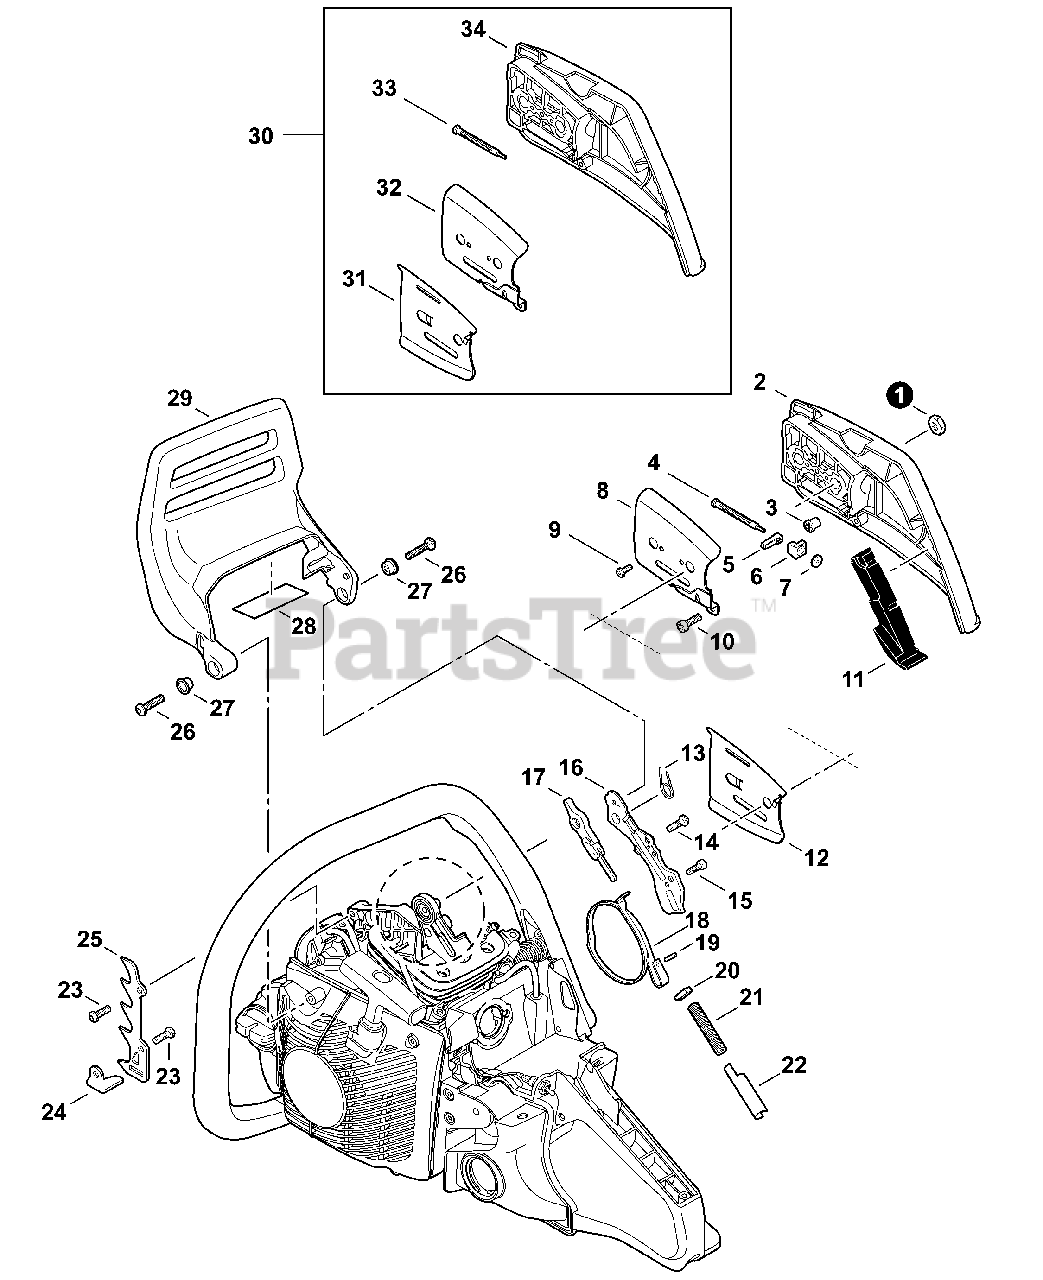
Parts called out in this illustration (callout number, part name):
2	GUARD, SPROCKET
3	GEAR, BEVEL
4	SCREW, CHAIN TENSION
5	TENSIONER, CHAIN
6	COLLAR 8
7	GEAR, BEVEL
8	PLATE, GUIDE - OUTER
9	SCREW 3×6
10	BOLT, TORX 4×12
11	CUSHION
12	PLATE, GUIDE - INNER
13	SPRING, TORSION
14	BOLT, TORX 5×16
15	BOLT, TORX 4×12
16	COVER, BRAKE
17	CONNECTOR, BRAKE
18	BAND, BRAKE
21	SPRING, COMPRESSION Ø12×70.5
22	PLATE, SIDE
23	BOLT, TORX 5×16
24	CHAIN CATCHER
25	SPIKE, BUMPER
26	BOLT, TORX 5×16
27	COLLAR 11.2×16.2×T0.6
28	SHIELD, HEAT 75×27×0.15
29	LEVER, BRAKE
30	GUARD KIT, SPROCKET
31	PLATE, GUIDE - INNER
32	PLATE, GUIDE - OUTER
33	SCREW, CHAIN TENSION 63 MM
34	GUARD, SPROCKET
